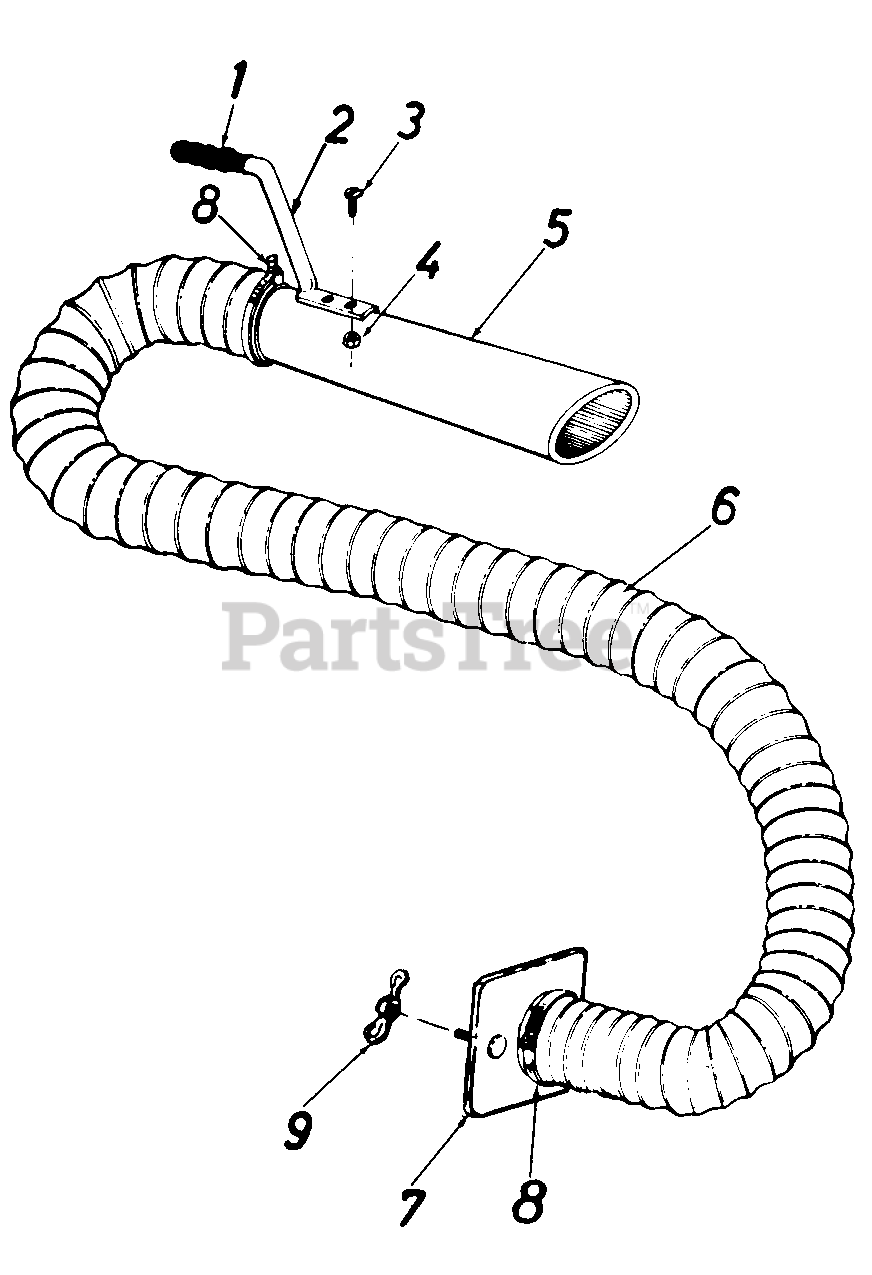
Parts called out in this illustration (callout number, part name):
1	Handle Grip
2	Handle
3	TrussSems Scr. 10-24x 1/2" Lg.*
4	Hex Nut 10-24 Thd.*
5	Hose Nozzle
6	Flexible Hose 4" Dia. x 10' Lg.
7	Hose Adapter Plate
8	Hose Clamp - For 4" Dia. H ose
9	WingNut 1/4-2 Thd.
